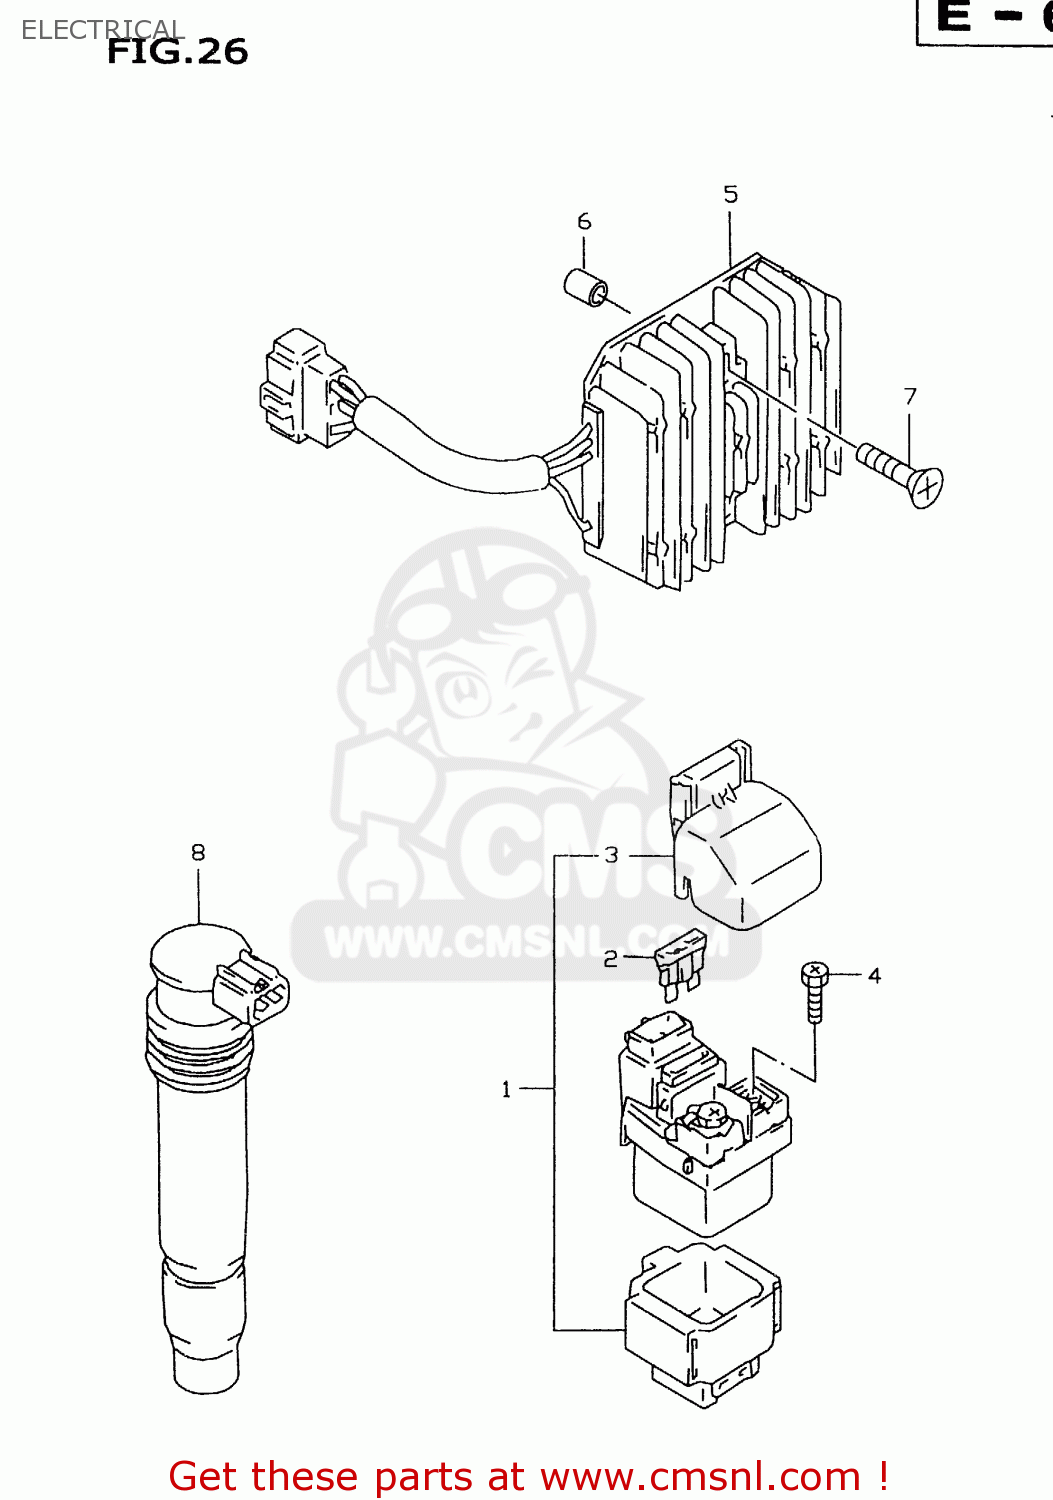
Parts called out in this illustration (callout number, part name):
1	RELAY ASSY,STARTING MOTOR
2	FUSE(30A)
3	COVER,STARTER RELAY
4	SCREW(6X8)
5	RECTIFIER ASSEMBLY
6	SPACER(6.5X10X7)
7	SCREW
8	COIL ASSY,IGNITION
